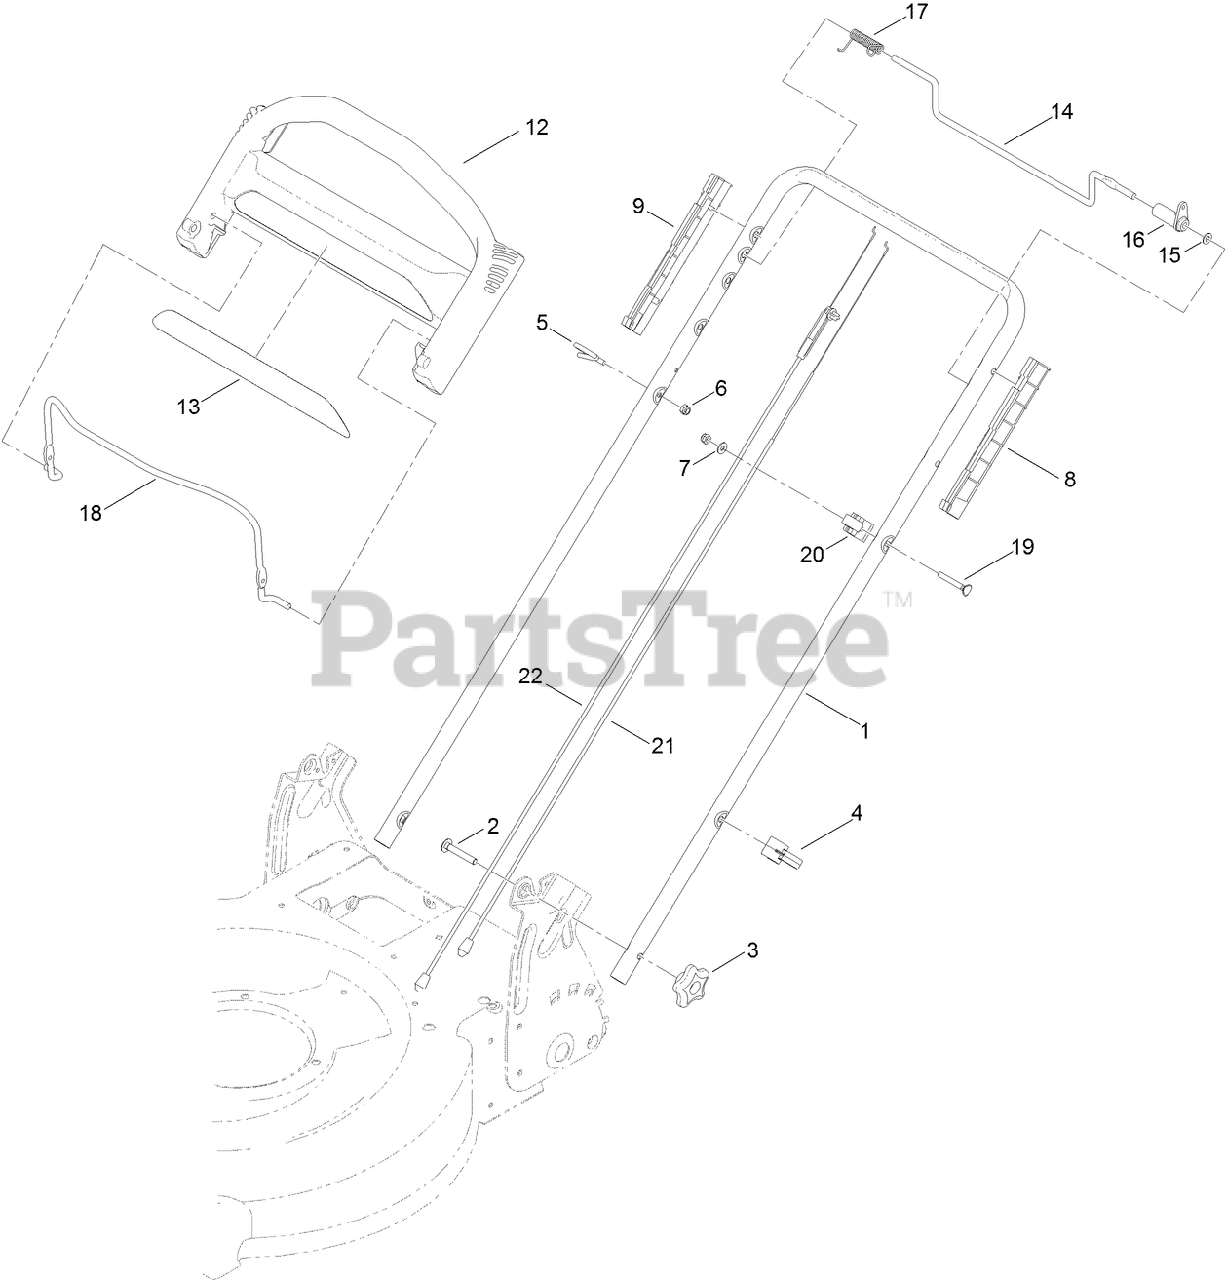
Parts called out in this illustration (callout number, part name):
2	BOLT-CARR
3	KNOB-HANDLE
4	GUIDE-CABLE
5	GUIDE-ROPE
6	NUT-LOCK, NI
7	WASHER-FLAT
8	GUIDE-LH
9	GUIDE-RH
12	HANDLE-CONTROL
15	WASHER-PLAIN
16	LEVER-TRACTION
19	SCREW
21	CABLE-TRACTION
22	CABLE-BRAKE
